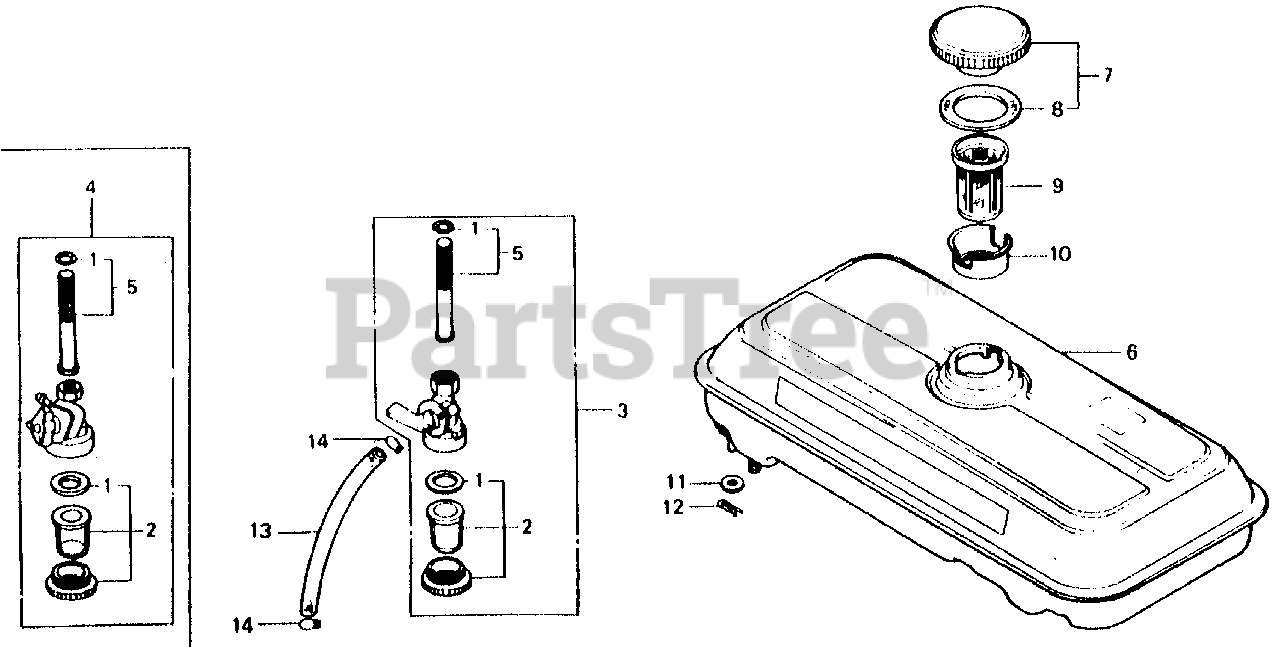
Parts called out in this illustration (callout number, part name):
1	GASKET SET, VALVE
2	CUP SET, FUEL STRAINER
3	PETCOCK ASSY.
4	PETCOCK ASSY.
5	SCREEN SET
6	TANK, FUEL *NH31* (MCKINLEY WHITE) (NOT AVAILABLE)
7	CAP, FUEL FILLER
8	GASKET, FUEL FILLER CAP
9	FILTER, FUEL
10	HOLDER, FUEL FILTER
11	WASHER, FLAT (20MM)
12	PIN, LOCK (8MM)
13	BULK HOSE, FUEL (4.5X3000) (4.5X120)
14	CLIP, TUBE (B8)
